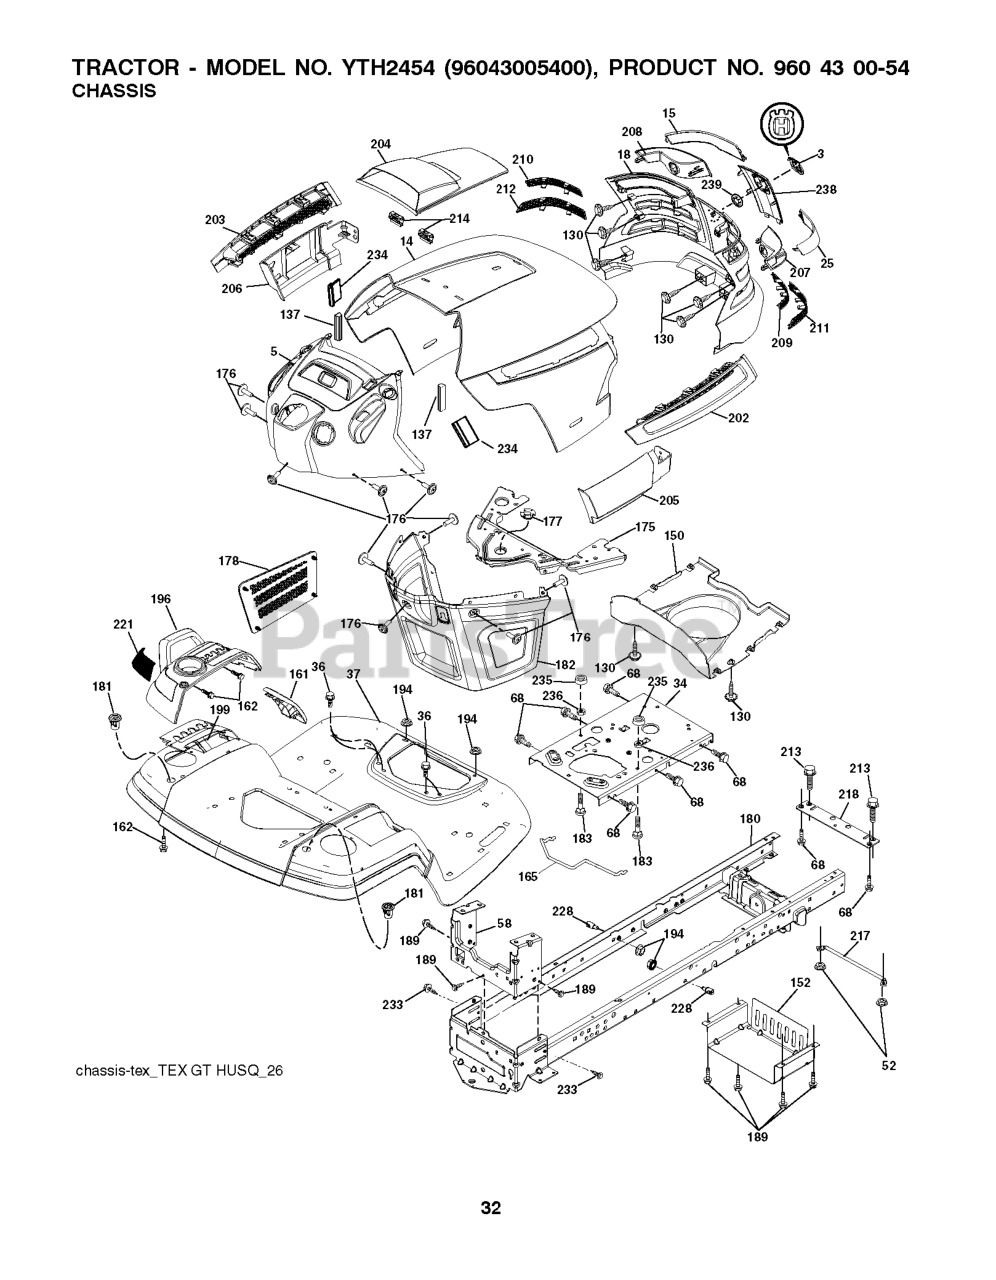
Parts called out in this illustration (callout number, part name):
3	RP LOGO
5	DASH.ASM.HUSQ.GT.E.RECT.W/CK
14	HOOD
15	LENS.LH.TEX.GT.HUSQ.CL
18	GRILL.ASM.HUSQ.TG/CRD.W/TRIM
25	LENS.RH.TEX.GT.HUSQ.CL
34	PLATE.ENGINE.WELDED.CHASSIS
36	SCREW 5/16"
37	FENDER.PNT.TX.GT.CH/FW.ORANGE
52	LOCKNUT
58	DRAWBAR.UPPER.2PC,LRG.FENDER
68	Screw 5/16-18 x 1/2 Hex, Self Tapping 5/16-18 x 1/2
130	SCREW.#10 X 0.750.BOS
137	BUMPER DASH
150	AIR.DUCT.HOOD.TEX.GT.HUSQ
152	SHIELD.BROWNING.W/TEX
161	CONSOLE.FUEL.WINDOW.HU
162	SCREW.HI-LO.CONSOLE
165	SUPPORT.TANK.REAR.W/TEX
175	PLATE.CROSSMEMBER.HUSQ
176	SCREW.#10-24X5/8.RN.QU
177	BUSHING, STEERING
178	CARGO.ASM.NET.TXGT.W/C
180	CHASS.WLDMNT.TL.12GA/2P.48/54
181	BUSHING.MNT.FEND.CRGO.
182	DASH.LOWER.COMMON.12V.ADAPTOR
183	BOLT.5/16-18X1-1/4 FULL.THREAD
189	SCREW
194	NUT LOCK HEX FLANGE 5/16-18
196	RP CONSOLE.ASM.DECKLFT.W/
199	PLATE.DECK.LIFT.HUSQVARNA.GT
202	VENT.SIDE.HOOD.HUSQ.RH.GREY
203	VENT.SIDE.HOOD.HUSQ.LH.GRAY
204	HOOD VENT
205	SKIRT.HOOD.SIDE.HUSQ.RH.GREY
206	SKIRT.HOOD.SIDE.HUSQ.LH.GREY
207	BEZEL.RH.TEX.GT.HUSQ
208	BEZEL.LH.TEX.GT.HUSQ
209	INSERT.HEX.GRILL.HUSQ.GREY
210	INSERT.HEX.GRILL.HUSQ.
211	INSERT.HEX.GRILL.HUSQ.
212	INSERT.HEX.GRILL.HUSQ.
213	BOLT
214	CLIP.RETAINER.TINNER.
217	ROD.PIVOT.HOOD
218	X-PIECE.HOOD.STOP.NON/
221	REFLECTOR.LH.TEX GT HU
228	STUD.FASTNER.W/ANTI-ROTATE
233	BOLT.SHOULDER
234	BUMPER.HOOD.TEX.HUSQVARNA
235	SPACER FENDER
236	NUT.CENTERLOCK.5/16-
238	TRIM.HUSQ.TG/CRD.SERVICE
239	NUT PUSH M
